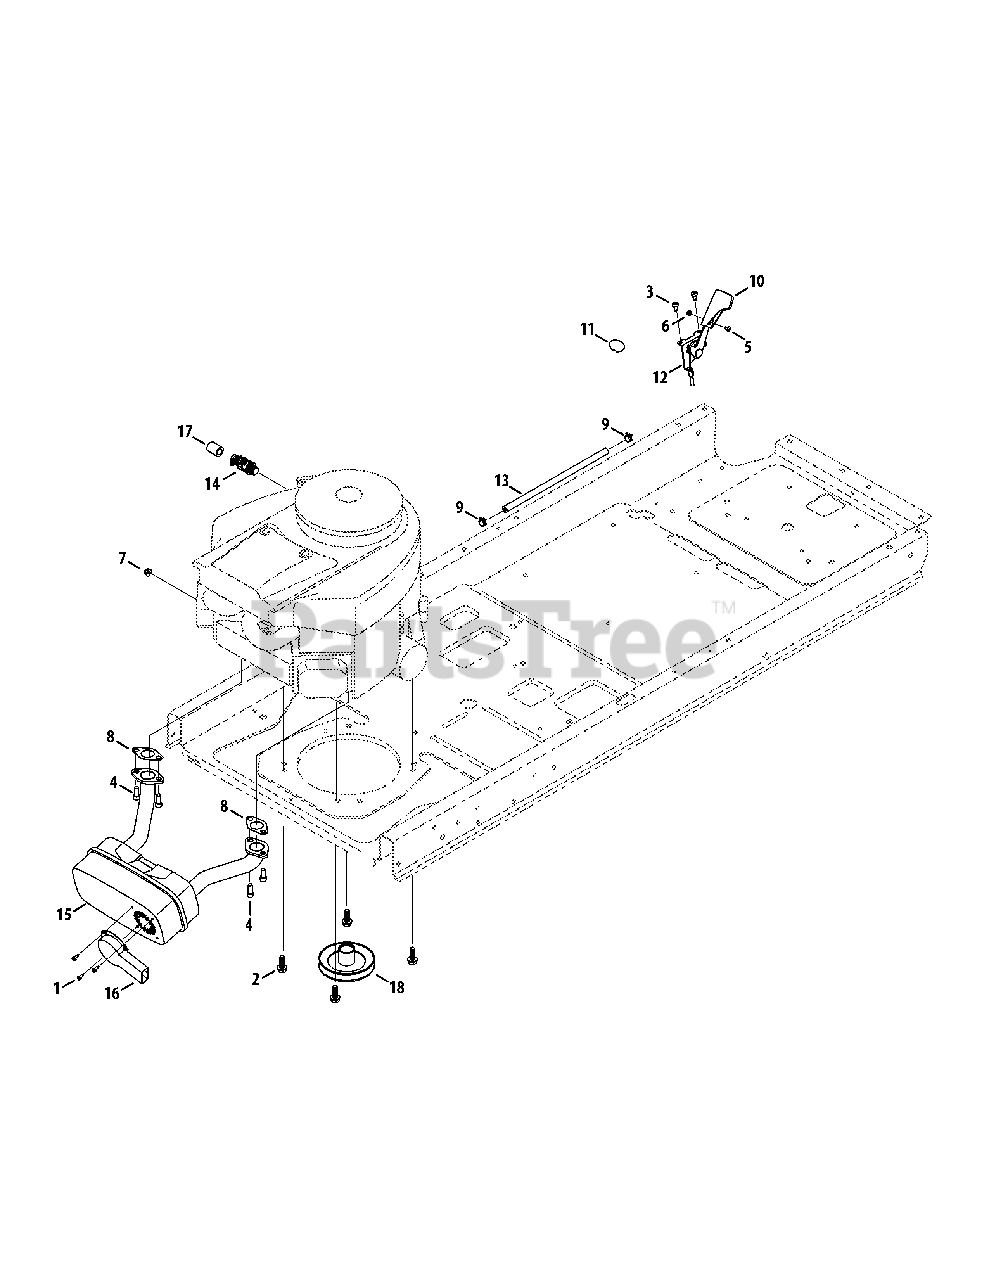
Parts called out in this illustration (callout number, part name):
1	Hex Washer Screw, #8-18 x .500
2	Hex Washer Screw, 3/8-16 x 1.00
3	Screw, 1/4-20 x .50
4	Socket Head Screw, 5/16-18 x .750
5	Screw, #8-32 x .375
6	Hex Nut, #8-32
7	Flange Lock Nut, 1/4-20
8	Exhaust Gasket
9	Hose Clamp, .490 Dia.
10	Throttle Control Knob
11	Choke Plug
12	Throttle/Choke Control Cable
13	Fuel Hose, 1/4
14	Oil Drain
15	Muffler, Intek Twin
16	Muffler Deflector Long
17	Oil Drain Hose
18	Engine Pulley
